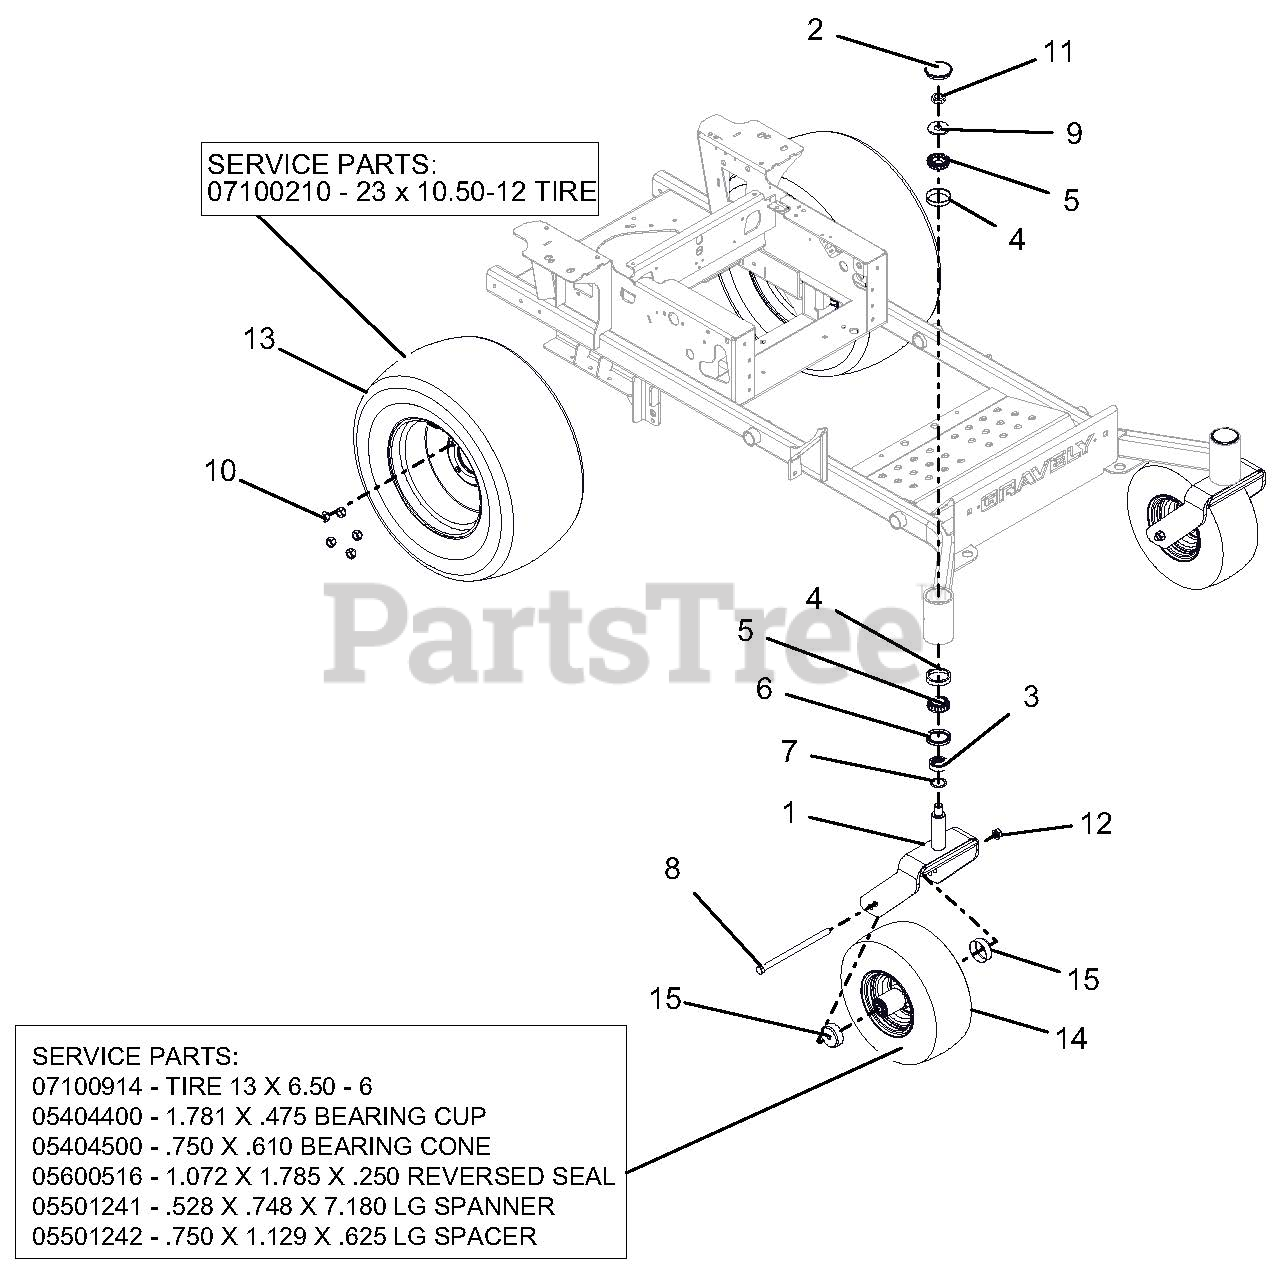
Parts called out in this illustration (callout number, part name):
1	WMT, CASTER FORK - RED
2	CAP, DUST
3	SPCR, FRONT CASTER FORK
4	BRG, CUP 2.328 X .465
5	BRG, CONE 1.250 X .660
6	SEAL, OIL 1.75 X 2.332 X .312
7	O-RING, .139 W X 1.234 ID
8	BLT-HEX .50-13X9.00 GR5 YWZC
9	WSHR-FL-STL.812X2.00X.148YWZC
10	NUT, LUG .500-13
11	@NUT-LK-CTR-JAM .75-16 YWZC
12	NUT, LK-TOP-FLG .50-13 YWZC
13	ASSM TIREWHEEL, 23X10.5-12
13	23 X 10.00-12 TIRE
14	TIRE/WHEEL, 13 X 6.50-6 SMOOTH
14	TIRE 13 X 6.50-6
14	3/4 BEARING CUP
14	3/4 BEARING CONE
14	1.072 X 1.785 X .250 REVERSED SEAL
14	.528 X .748 X 7.180 LG SPANNER
14	.750 X 1.129 X .625 LG SPACER
15	SHIELD, WHEEL BEARING
